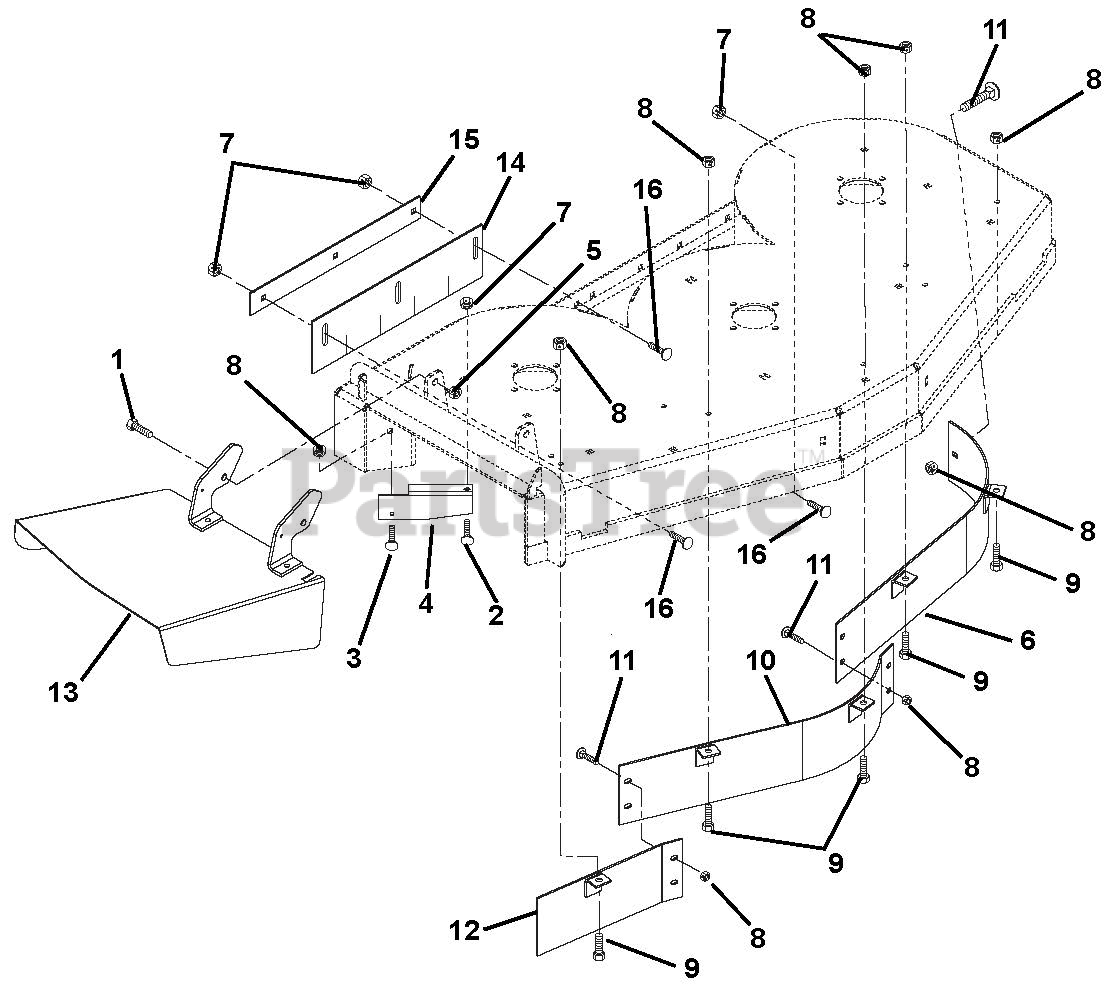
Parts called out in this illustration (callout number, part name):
1	Bolt, Hex .50-13 x 1.25 Grade 5
2	Bolt, Round Head Square Neck .38-16 x .75 Grade 5
3	Bolt, Round Head Square Neck .31-18 x 1.00 Grade 5
4	Deflector 44"/48"
5	Nut, Locking-Nylon .50-13
6	Weldment, Upper Baffle Left
7	Nut, Locking-Top-Flange .38-16
8	Nut, Locking-Top-Flange .31-18
9	Bolt, Hex .31-18 x .75 Grade 5
10	Weldment, Upper Baffle Center
11	Bolt, Round Head Square Neck .31-18 x .75 Grade 5
12	Weldment, Right Hand Baffle-Upper
13	Chute, Discharge
14	Skirt, Rubber
15	Strip, Striper Mount
16	Bolt, Round Head Square Neck .38-16 x 1.00 Grade 5
